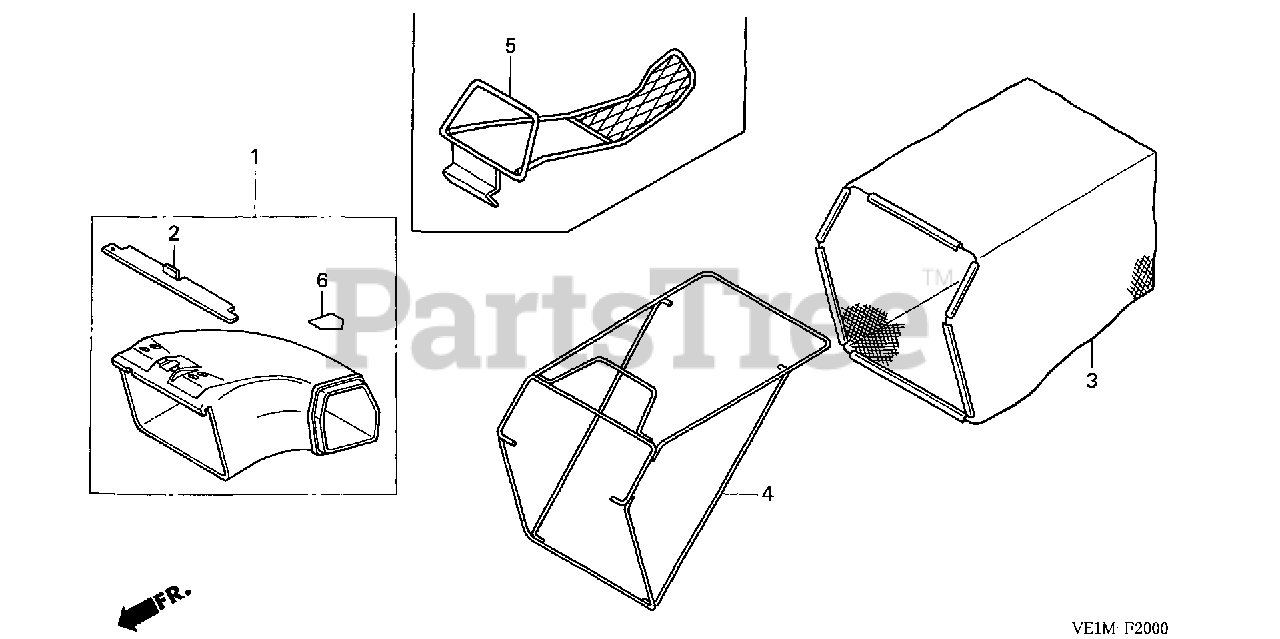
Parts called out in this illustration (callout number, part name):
1	CHUTE KIT, SIDE DISCHARGE
2	BRACKET, MOUNTING
3	FABRIC, GRASS BAG
4	FRAME, BAG
5	SHREDDER, LEAF
6	LABEL B, HOUSING CAUTION
